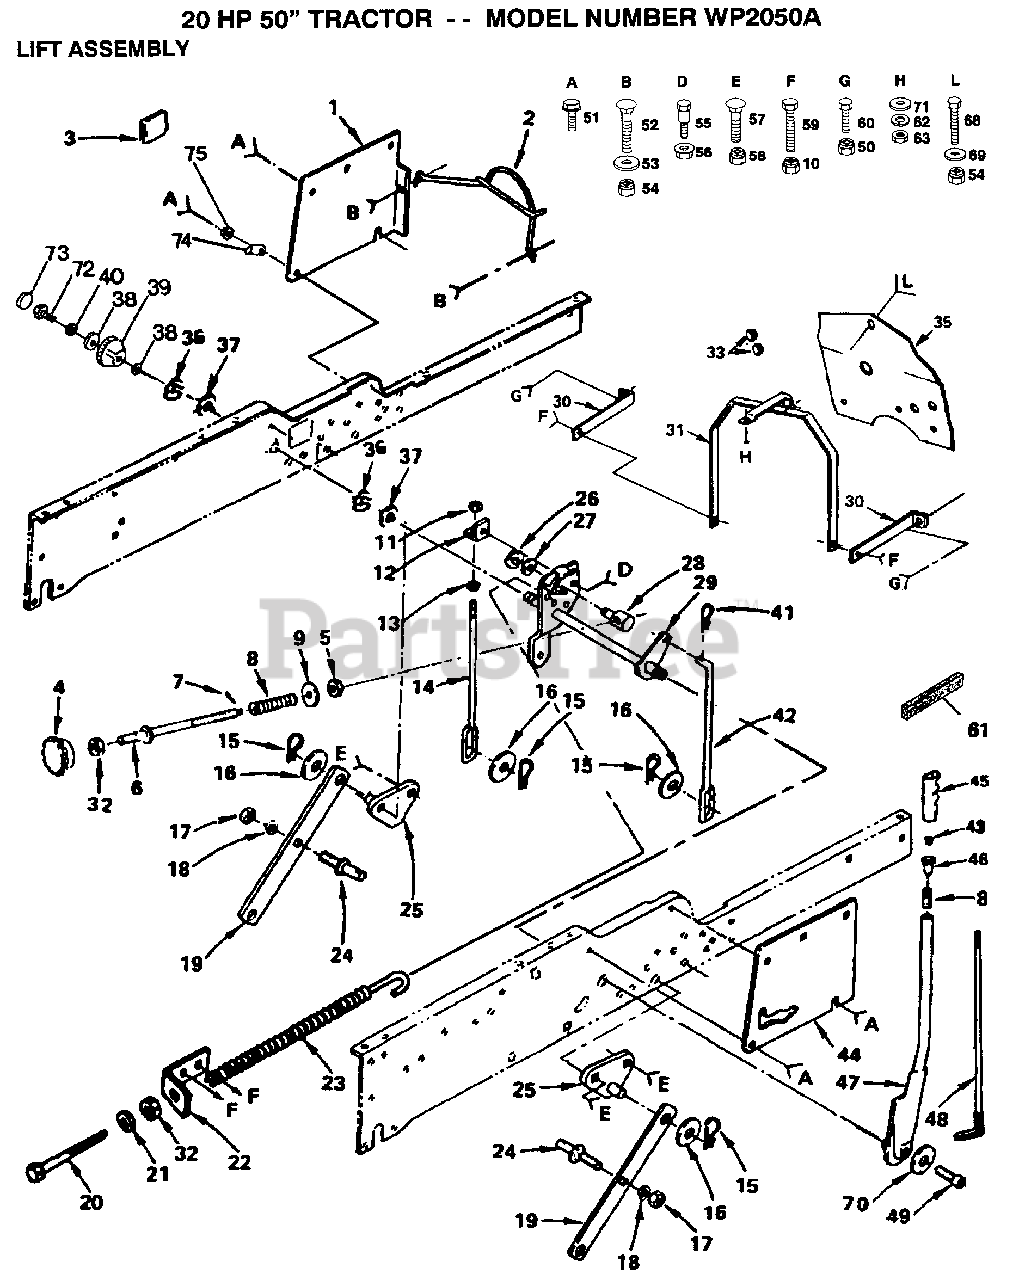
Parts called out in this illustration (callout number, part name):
2	"GUARD, BELT"
3	COVER ACCESS
5	NUT T
6	ROD ADJ. T
8	SPRING T
9	WASHER
11	NUT
12	BRACKET T
13	NUT.HEX.3/8-16UNC
14	LINK-LIFT MOW T
15	SPRING H
17	NUT
18	LOCKWASHER
19	SUSPENSION ARM GT
20	BOLT-ADJ SPRING T
21	WASHER
24	PIVOT STUD GT
25	SUSP BRACKET T
26	KLIP RING
27	WASHER
28	TRUNION LT
29	SHAFT ASS'Y LIFT
30	BRACKET T
32	NUT
35	"SHIELD HEAT, BASE"
36	E-RING
37	WASHER
38	WASHER
39	HEIGHT INDICATOR
40	LOCKWASHER
42	LIFT LINK RH T
45	GRIP
48	LEVER ROD LT
49	"BOLT,HEX"
51	SCREW LT
52	BOLT
53	WASHER
55	SHOULDER BOLT T
56	NUT T
57	BOLT
58	LOCKNUT
59	BOLT
60	BOLT
61	FOAM STRIP T
68	BOLT
69	WASHER M
70	LOCKWASHER
71	WASHER PM
73	"PLUG,HOLE"
75	WASHER T
